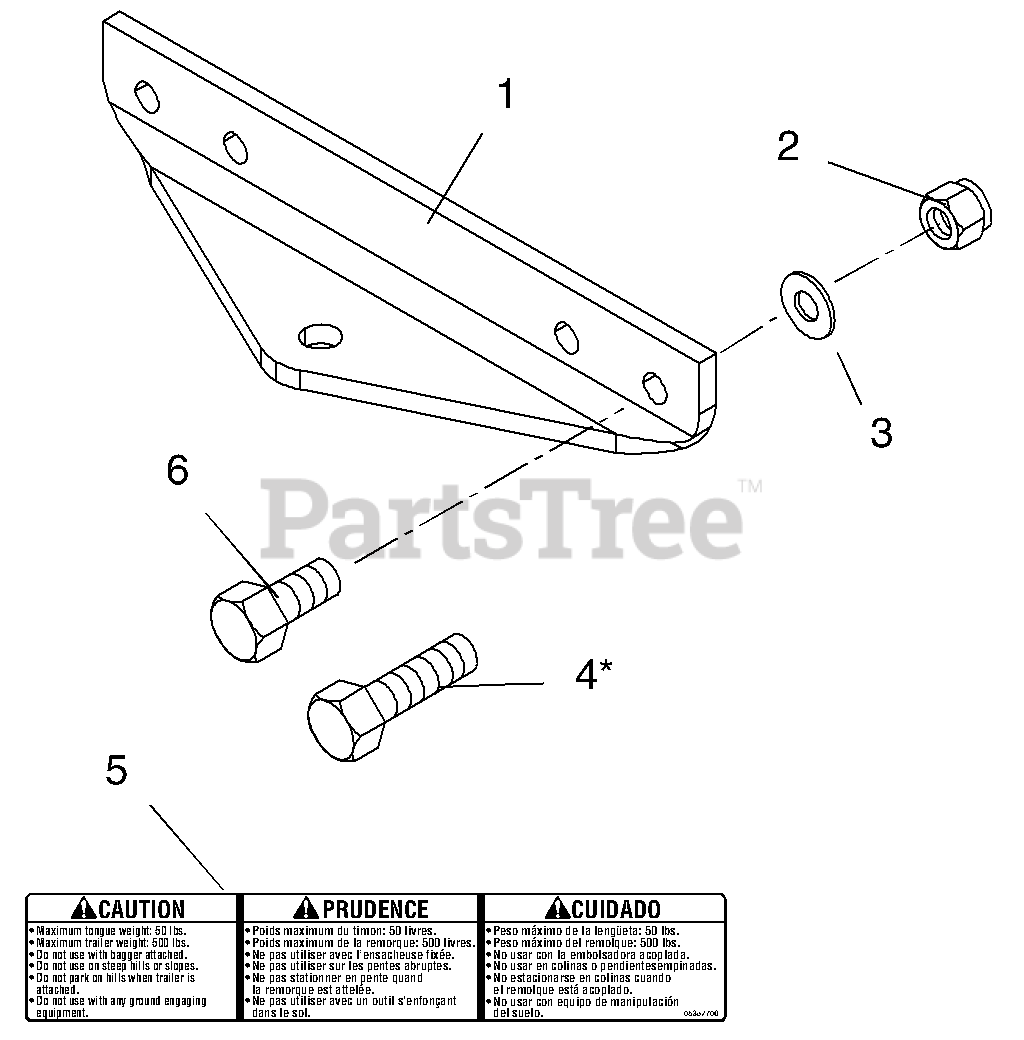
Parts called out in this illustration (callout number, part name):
1	Hitch Plate
2	1/2" Nylon Locknut
3	Flat Washer
4	1/2" x 3-1/4" Hex Bolt
6	1/2" x 1-1/4" Hex Bolt
